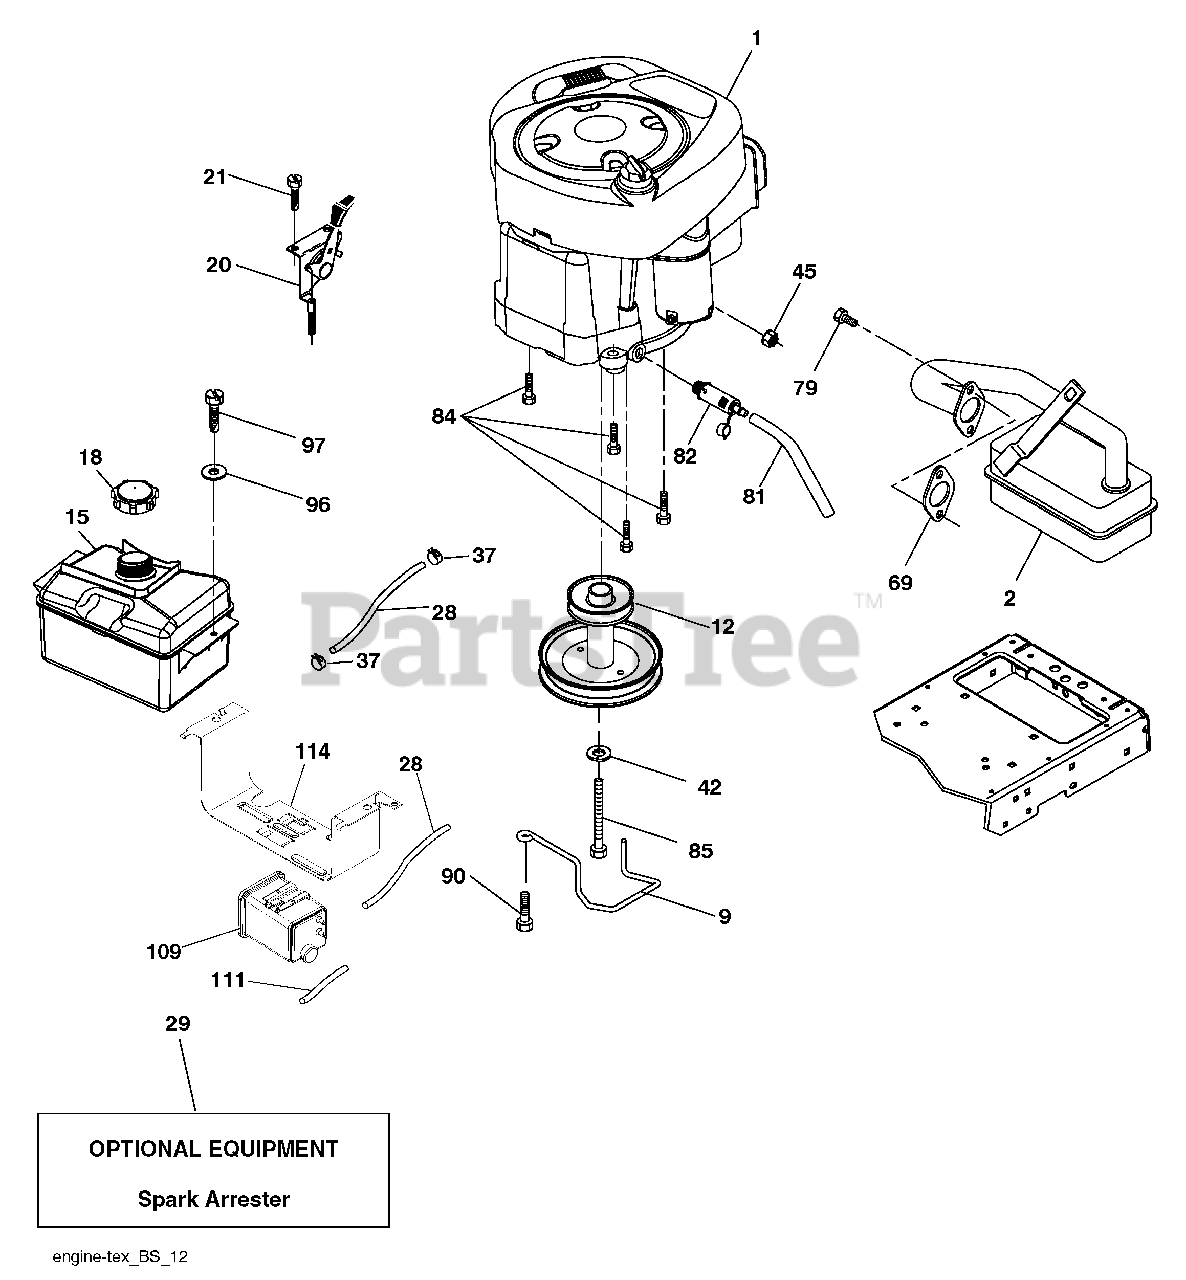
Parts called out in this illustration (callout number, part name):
2	Muffler
9	Keeper Belt Engine
12	Pulley Engine
15	Tank Fuel 1.50
18	Cap Asm
20	Control Throttle/Choke
21	Screw #10 x 0.750 BOS Thread
28	Fuel Line
29	Spark Arrester Kit
37	Clamp Hose
42	Washer Lock 7/16
45	Nut Keps Hex 1/4-20 unc
69	Gasket
79	Screw Socket Hd 5/16-18 x .75
81	Tube Drain Oil Easy
82	Plug Drain Oil
84	Screw 3/8-16 x 1-1/4
85	Bolt Hex 7/16-20 x 4 x Gr. 5-1.5
90	Screw 3/8-16 x 1.0
96	Washer 9/32 x 7/8 x 16 Ga.
97	Screw 1/4 - 20 x 3/4
109	Canister Carbon Filter Asm
111	Purge Line
114	Cradle Carbon Canister
